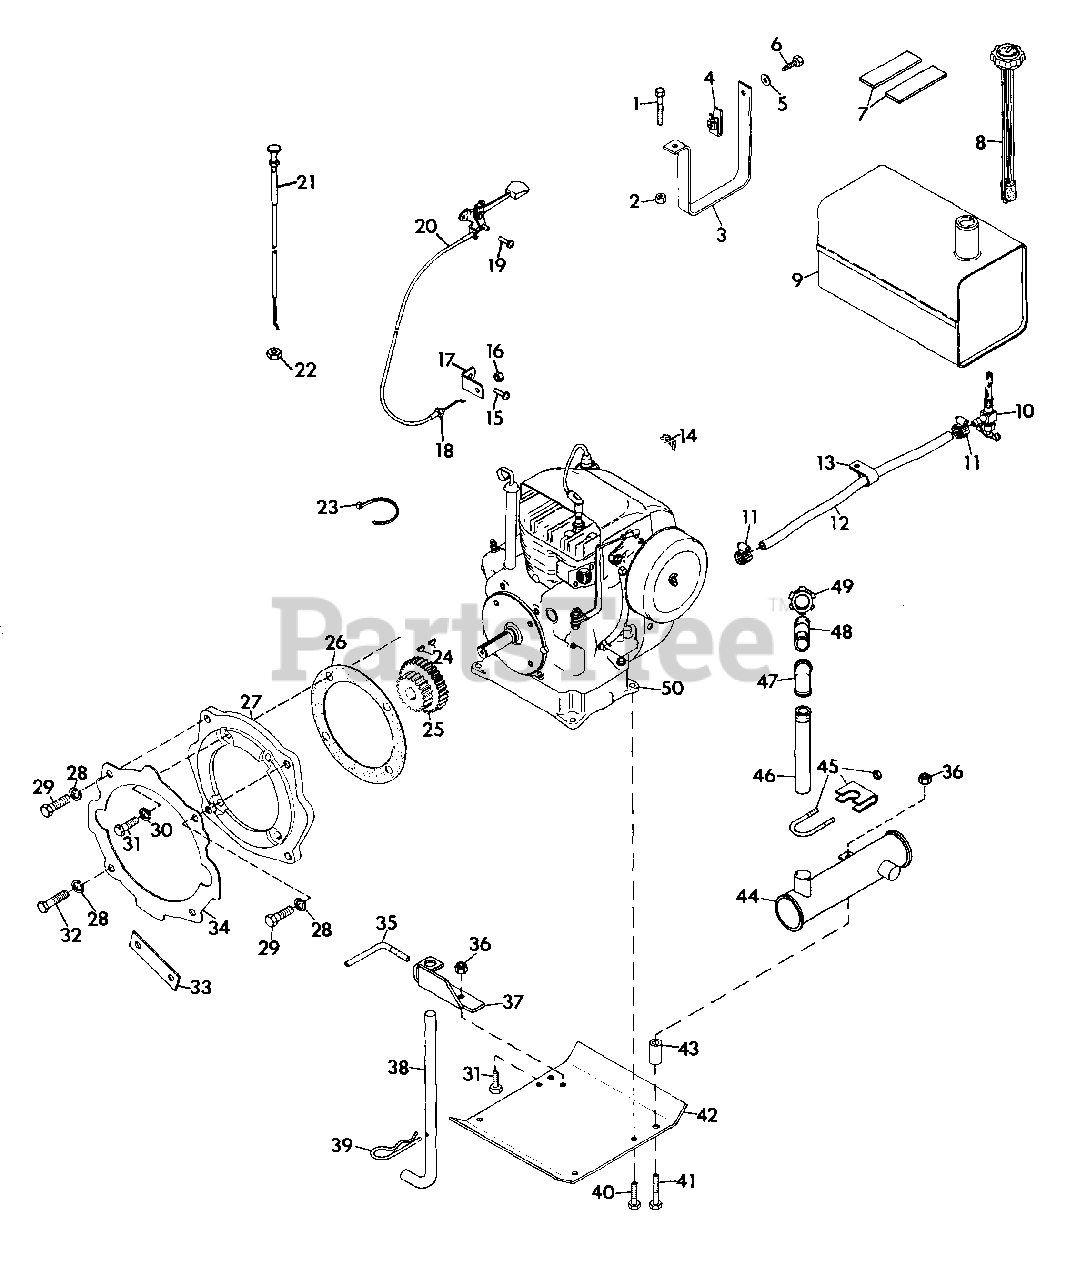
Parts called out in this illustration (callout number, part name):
1	BOLT, HEX 5/16-18X1.25
2	NUT, LOCK 5/16-18
3	STRAP, GAS TANK
4	NUT, RETAINER
5	WASHER, FLAT .343X.688X.065
6	BOLT, HEX 5/16-18X.75
7	PAD, GAS TANK
8	GAUGE, FUEL
9	TANK, FUEL
10	VALVE AND STRAINER
11	CLAMP, HOSE
12	LINE, FUEL
13	CLAMP, NYLON
14	CLIP, SPEED
15	SCREW, MACH. 1/4-20X.50
16	NUT, HEX 1/4-20
17	BRACKET
18	ADAPTOR, CONDUIT
19	SCREW, TAPPING 1/4-20X.50
20	LEVER, CONTROL
21	CONTROL, CHOKE
22	NUT, JAM 3/8-24 HEX
23	TIE, CABLE
24	KEY, WOODRUFF 5/32X.625
25	GEAR, 10/12 DP 21/30 TEETH
26	GASKET, ENGINE TO ADAPTOR
27	ADAPTOR, ENGINE
28	WASHER, LOCK 7/16
29	BOLT, HEX 7/16-14X1.50
30	WASHER, LOCK 3/8
31	BOLT, HEX 3/8-16X1.00
32	BOLT, HEX 7/16-14X1.25
33	STRAP
34	GASKET, CHASSIS TO ADAPTOR
35	HANDLE, ADJUSTING
36	NUT, LOCK 3/8-16
37	STAND, SUPPORT
38	STAND, KICK
39	PIN, HAIR
40	BOLT, HEX 3/8-16X1.50
41	BOLT, HEX 3/8-16X1.75
42	PLATE, SKID
43	BUSHING, .407X.625X.812
44	MUFFLER, KOHLER 16-HP
45	CLAMP, MUFFLER
46	NIPPLE, 1.25 PIPE 7.8 LG.
47	ELBOW, 1.25 PIPE
48	NIPPLE, 1.25 PIPE
49	NUT, CONDUIT 1.25" PIPE
50	ENGINE, 16-HP KOHLER
